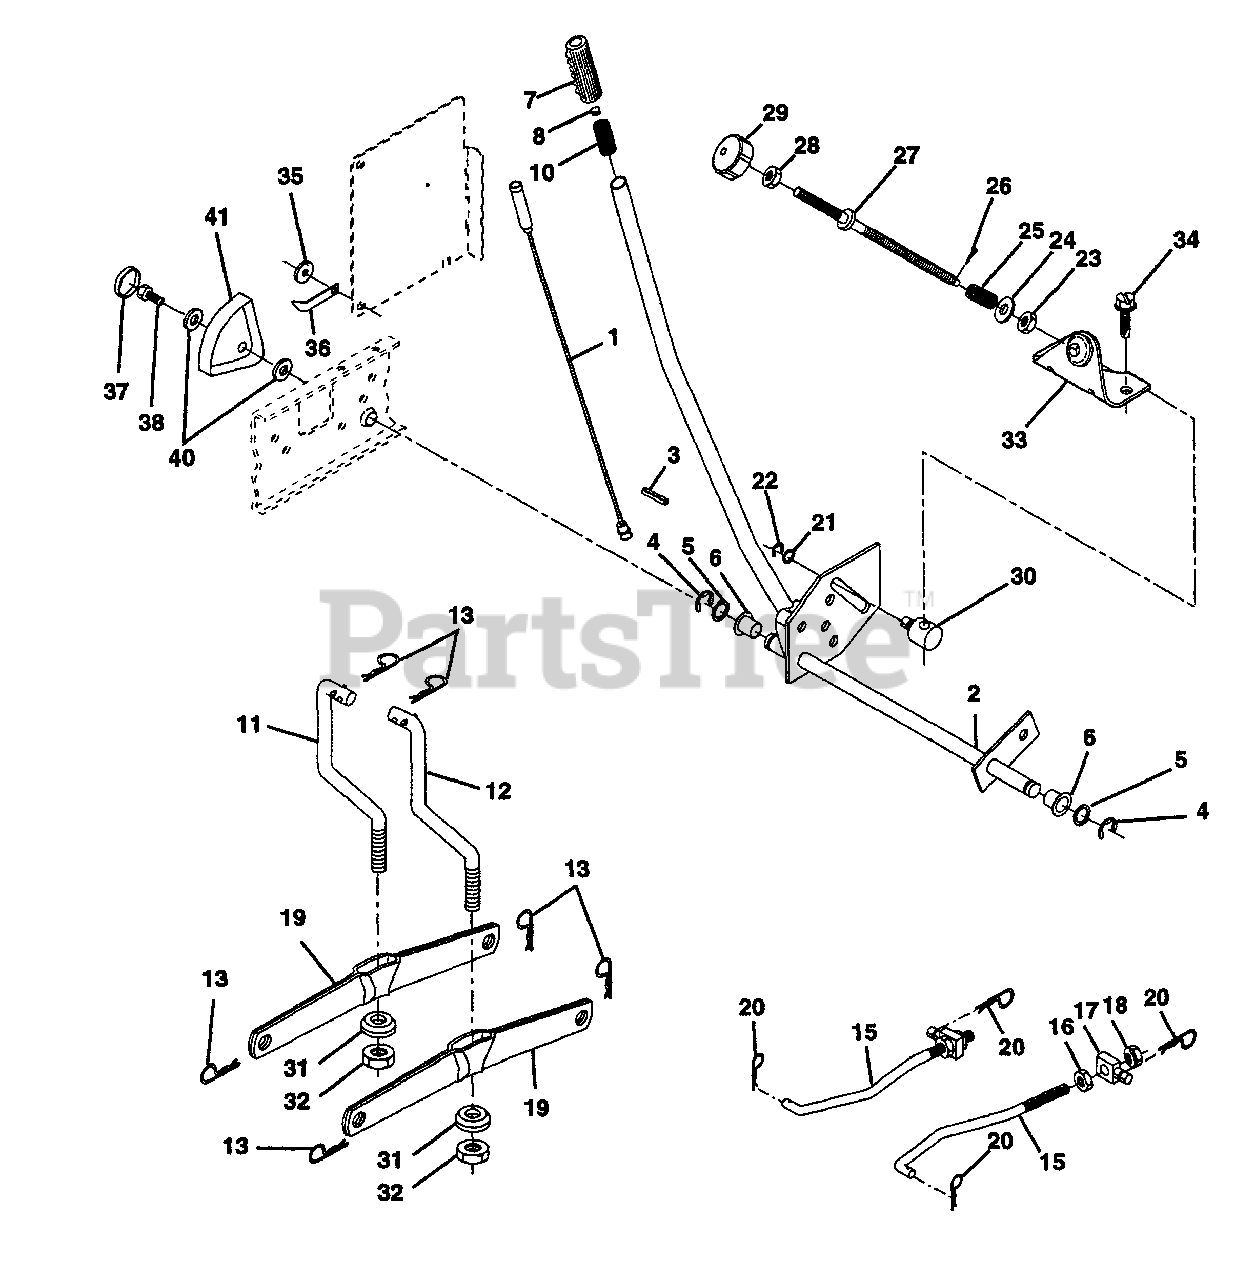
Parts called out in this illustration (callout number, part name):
1	Wire Asm Inner W/plunger 17 32
2	Handle Asm Lift LH Inf Hgt P/L
3	Pin Groove 1 500 Zinc
4	E Ring #5133-62
5	Washer 21/32 X 1 X 21 Ga
6	Bearing Nylon Blk 629 Id
7	Grip Handle Bicycle Matte Blk
8	Button Plunger Black
10	Spring Cprsn 3 750 Oiled
11	Link Lift LH
12	Link Lift RH
13	Retainer Spring
15	Link Front
16	Nut Jam Hex 1/2-13 Unc
17	Trunnion Blk Zinc
18	Nut Lock W/wsh 1/2-13unc
19	Arm Suspension Rear
20	Retainer Spring
21	Washer 15/32 3/4 X 16 Ga
22	Ring Klip #t5304-37
23	Nut Special
24	Washer 13/32 X 5/8 X 16 Ga
25	Spring 2-1/8"
26	Pin Cotter 3/32 X 1/2
27	Rod Adj Lift Zinc 7 49 Wrk Lg
28	Nut Hex Jam 3/8-16 Unc
29	Knob inf 3/8-16 Unc Blk W/sym
30	Trunnion Dp Stop Dbl Thds PLT
31	Bearing pvt. Lift Spherical
32	Nut Crownlock 3/8-24
33	Bracket Stop inf Hgt
34	Screw Thdtol 3/8-16 x 1/2 Ty-tt
35	Washer Nylon .44 x .75 x 032
36	Pointer pnt height Ind.
37	Plug hole Blk 1.485/1.515 Dia
38	Screw Thdrol 5/16-18 X 3/4
40	Washer 11/32 x 1-1/2 10 Ga
41	Scale Ind. Height Black
